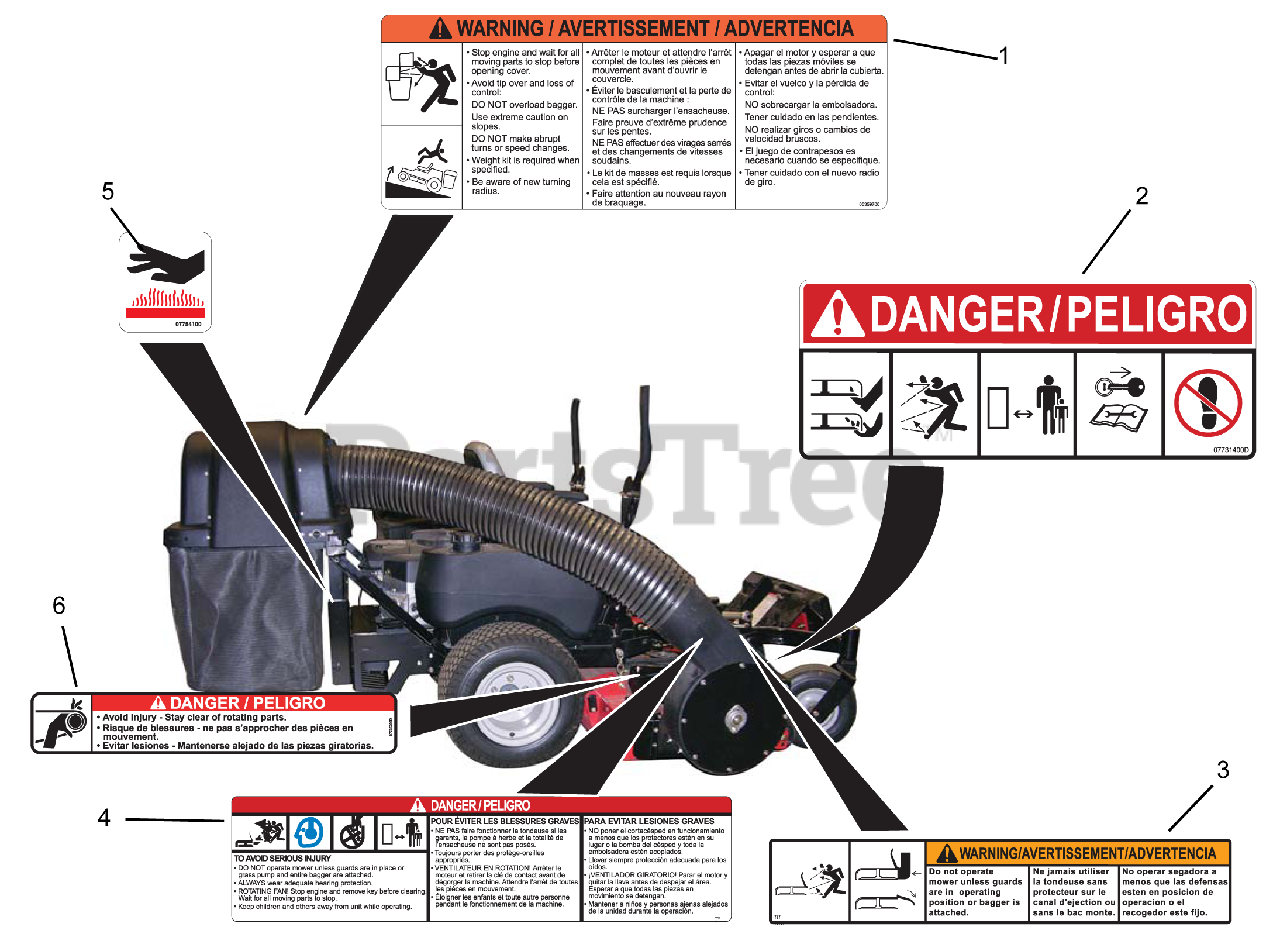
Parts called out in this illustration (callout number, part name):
1	DECAL, BAGGER COVER
2	DECAL, MOWER PAN DANGER
3	DECAL, WARNING
4	DECAL-CAUTION, GRASS PUMP
5	DECAL, HOT SURFACE
6	DECAL- DANGER
